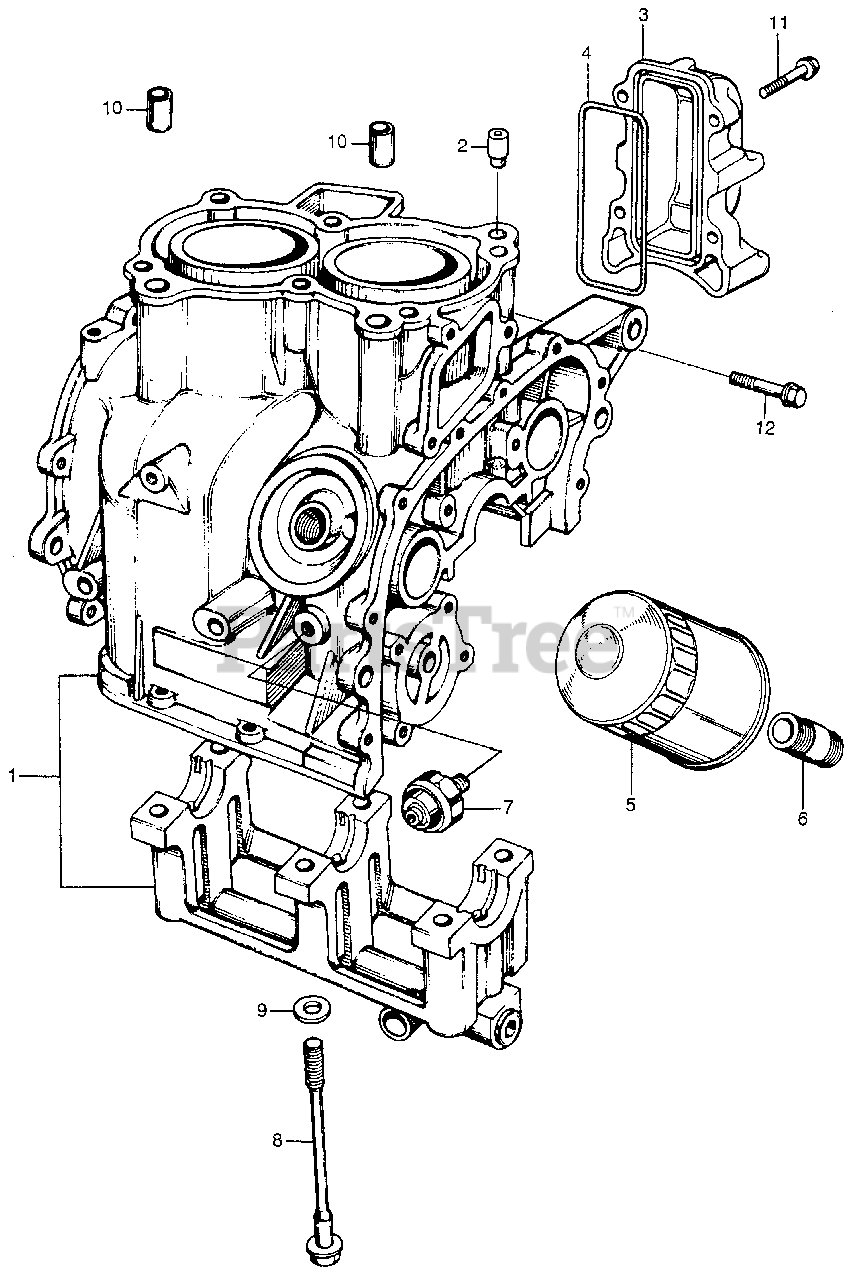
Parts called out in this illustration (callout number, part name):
1	BLOCK SET, CYLINDER
2	NOZZLE (NOT AVAILABLE)
3	COVER, BALANCER
4	GASKET, BALANCER
5	FILTER, OIL
6	PIPE, OIL PASSAGE
7	SWITCH, PRESSURE
8	BOLT, BEARING CAP
9	WASHER, SPECIAL (23x11x2.3)
10	PIN A, DOWEL (14X20)
11	BOLT, FLANGE (6X25)
12	BOLT, FLANGE (8X40)
